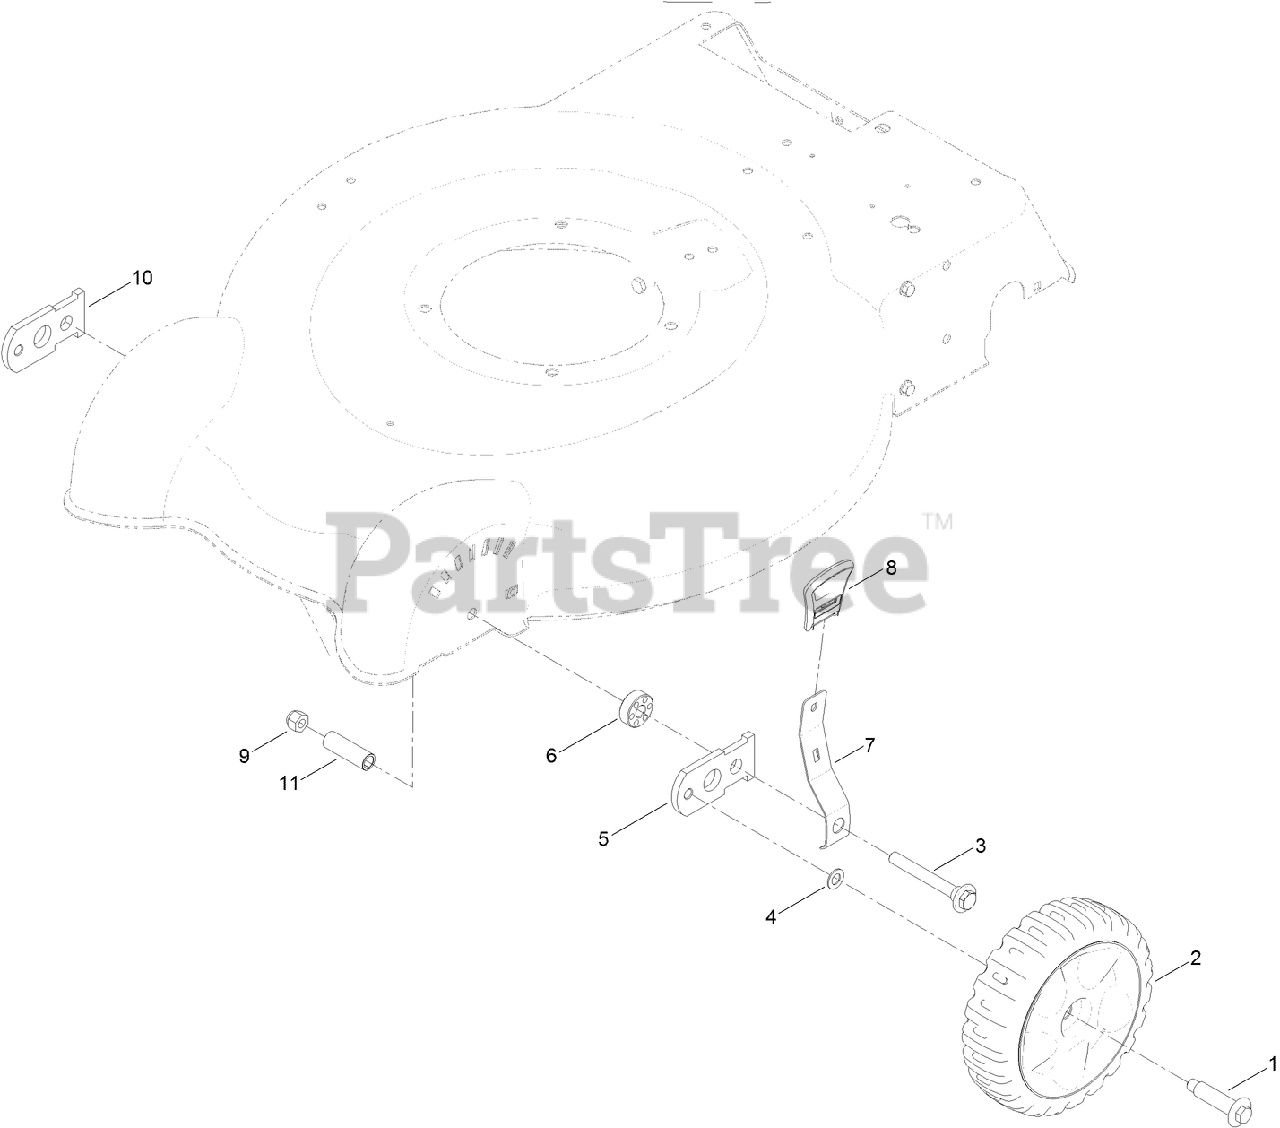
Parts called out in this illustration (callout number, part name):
1	BOLT-SHOULDER
2	7 INCH WHEEL AND TIRE ASM
3	BOLT-SHOULDER
4	WASHER
5	ARM-PIVOT, RH
6	SPACER-ARM, PIVOT
7	ARM-SPRING, FRONT
8	KNOB-HOC
9	NUT-LOCK, NI
10	ARM-PIVOT, LH
11	SPACER-BAFFLE, FRONT
